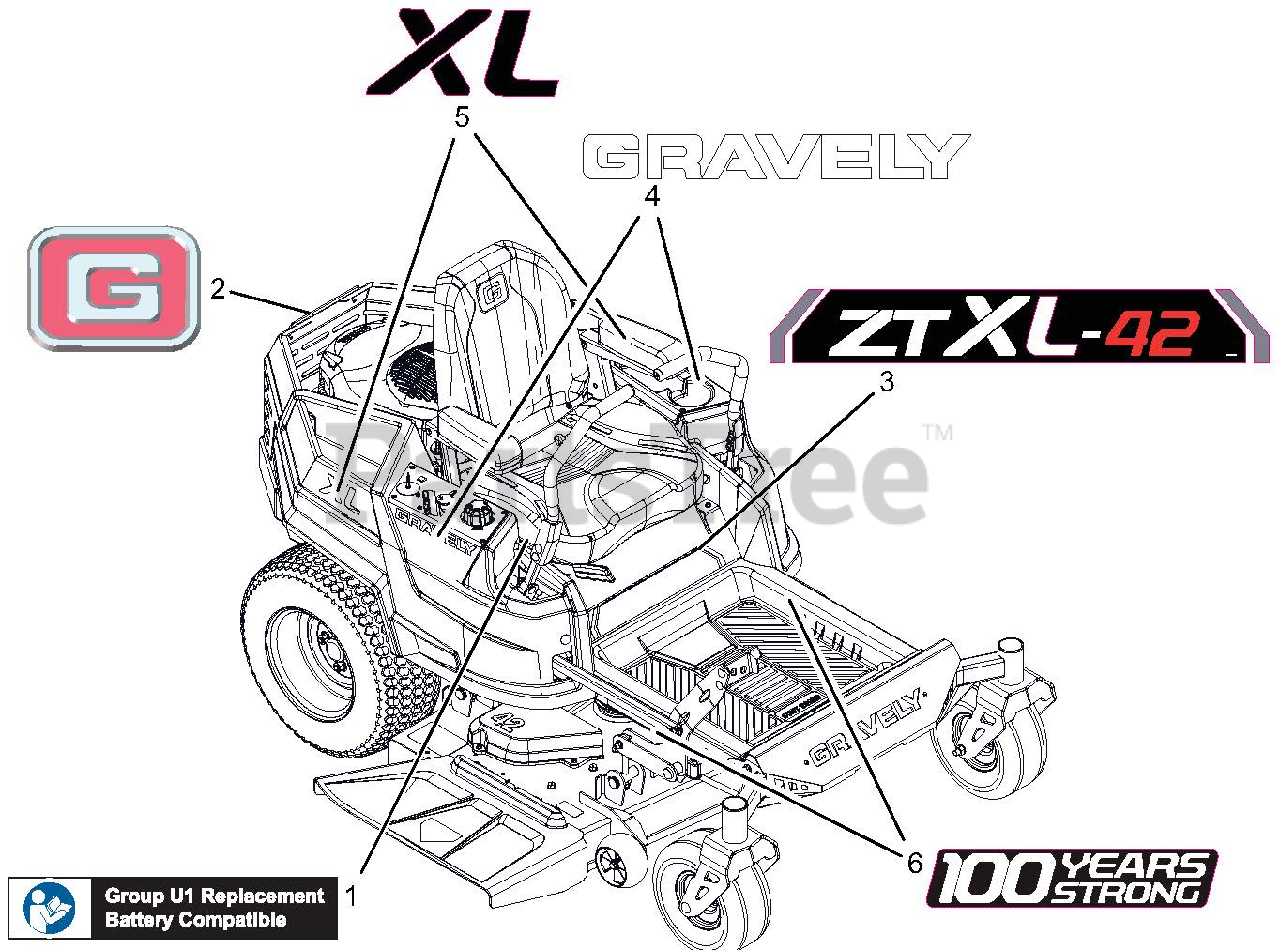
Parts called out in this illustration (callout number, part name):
1	DECAL, U1 REPLACEMENT BATTERY
2	DECAL, GRAVELY BRAND
3	DECAL, ZT XL 42"
4	DECAL, 9.5" GRAVLEY LOGO
5	DECAL, SIDE PANEL "XL"
6	DECAL, GRAVELY 100 YEAR
